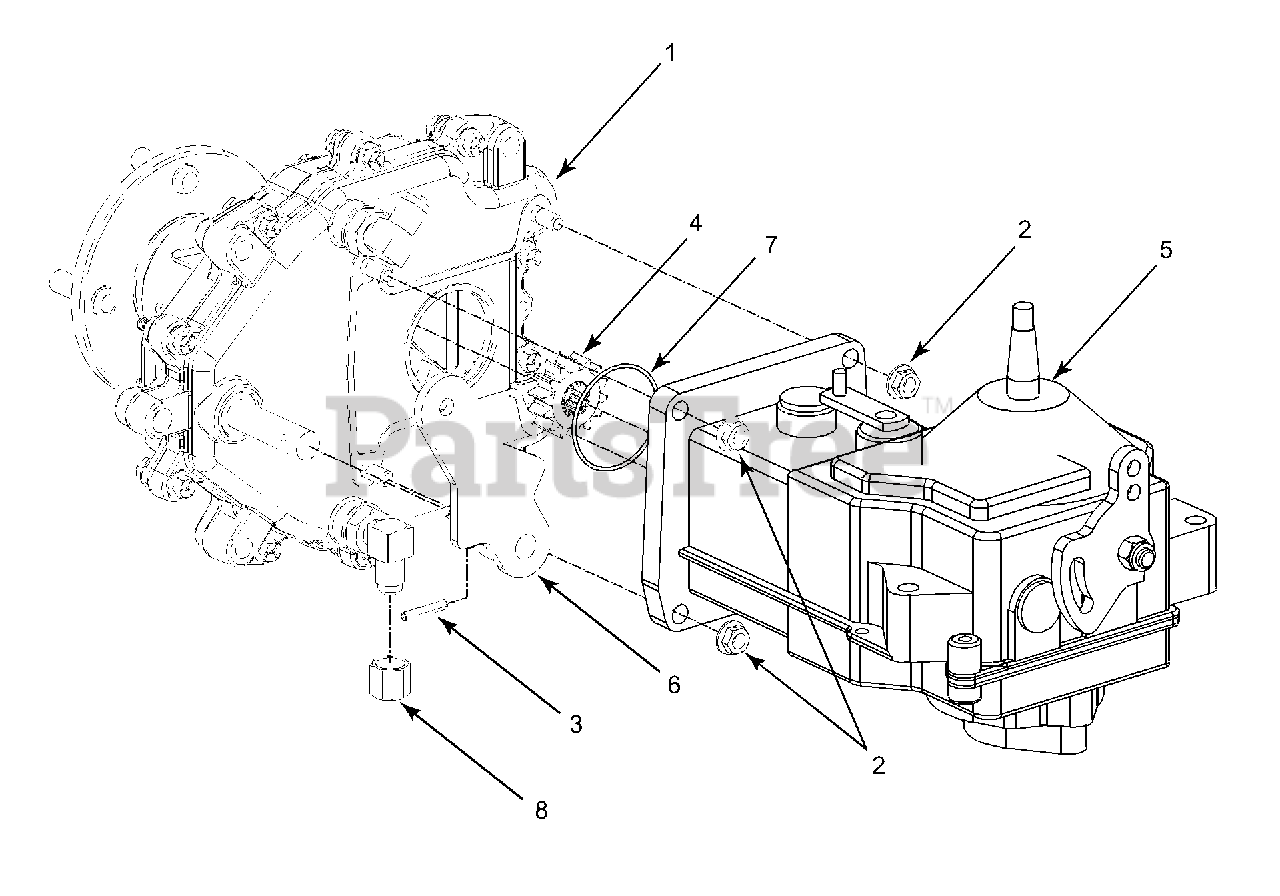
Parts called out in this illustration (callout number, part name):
1	Drive Ass'y Complete
2	Hex Flange Lock Nut 5/16-18
3	Spirol Pin 3/16 x 1.25
4	Spur Gear 14T
5	Hydro Transmission
6	Parking Brake Lever
7	O-Ring 2.0 Dia.
8	Cap Nut 3/8
